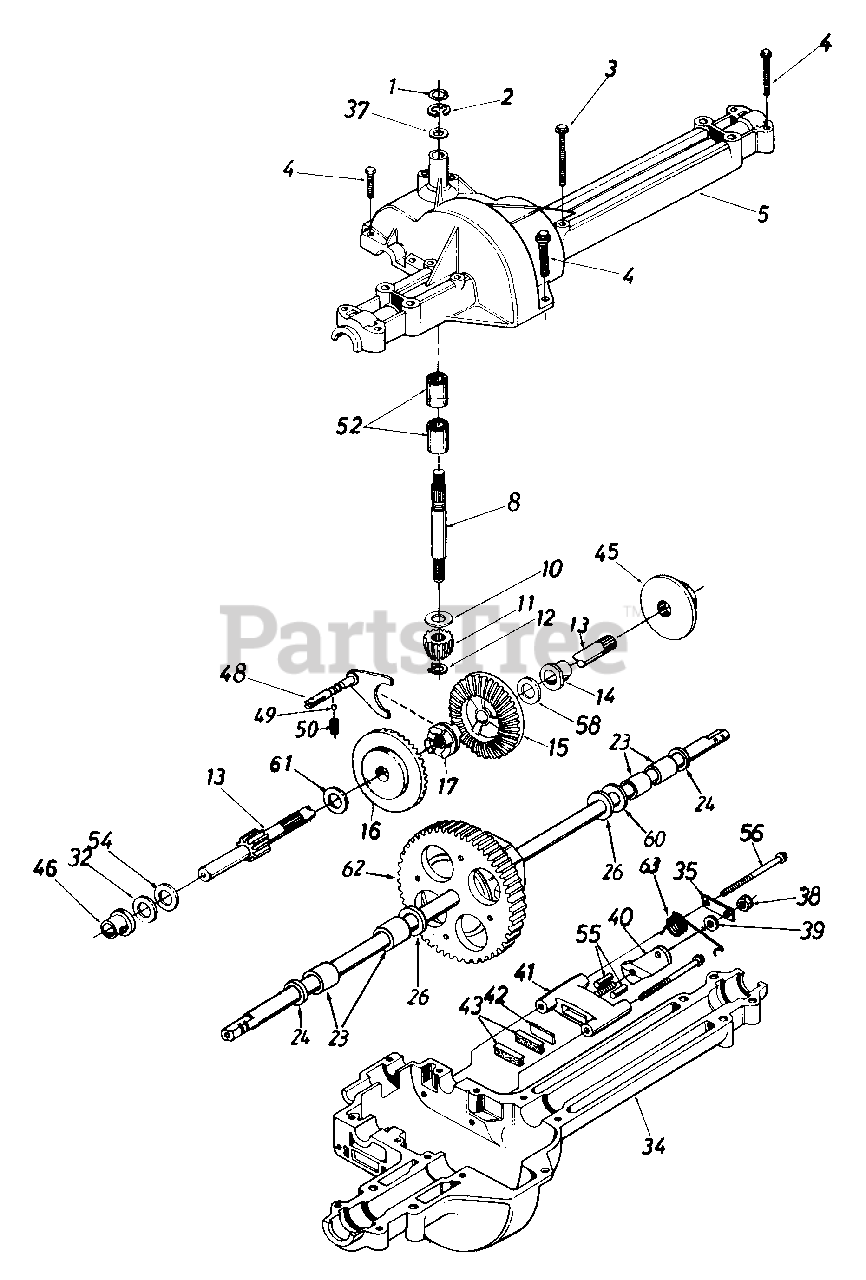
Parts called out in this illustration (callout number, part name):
3	Hex Wash. TT-Tap Scr. 1/4-20 x 1.75" Lg.
4	Hex Tap Scr. 1/4-20 x 1.25" Lg.
5	Upper Housing
10	Thrust Washer 5/8" I.D. x 1.25" O.D.
11	Pinion Input 14T
12	Retaining Ring
13	Drive Shaft - R.H. Brake
14	Flange Brg. 5/8" I.D. x 3/4" Lg.
15	Bevel Gear 42T Small I.D.
16	Bevel Gear 42T Large I.D.
17	Clutch Collar
23	Sleeve Bearing 3/4" I.D. x 1.0" Lg.
24	Oil Seal 3/4" I.D.
26	Fl-Wash. .760" I.D. x 1.5" O.D.
32	Thrust Wash. 5/8" I.D. x 1" O.D. x .025" Thk.
34	Lower Housing
35	Anti-Rotation Brkt.
37	Fl-Wash. 5/8" I.D. x 1" O.D. x .020" Thk.
38	Hex Nut 5/16-24 Thd.
39	Fl-Wash. .344" I.D. x .875" O.D.
40	Actuating Arm
41	Brake Yoke
42	Puck Plate
43	Brake Puck
46	Flange Bearing 5/8" I.D. x 15/16" Lg.
48	Shift Fork Ass'y.
49	Ball Detent .250" Dia.
50	Spring Detent
52	Needle Brg. 5/8" I.D. x 1/2" Lg.
54	Fl-Wash. 5/8" I.D. x 1" O.D. x .020 Thk.
55	Actuating Pin 5/16" Dia.
56	Hex Wash Hd. Self-Tap Scr. 1/4-20 Thd.
58	Fl-Wash. 5/8" I.D. x 1" O.D. x .020 Thk.
60	Fl-Wash. .76" I.D. x 1.5" O.D. x .010" Thk.
61	Thrust Washer
62	Differential Ass'y.
63	R.H. Brake Spring
